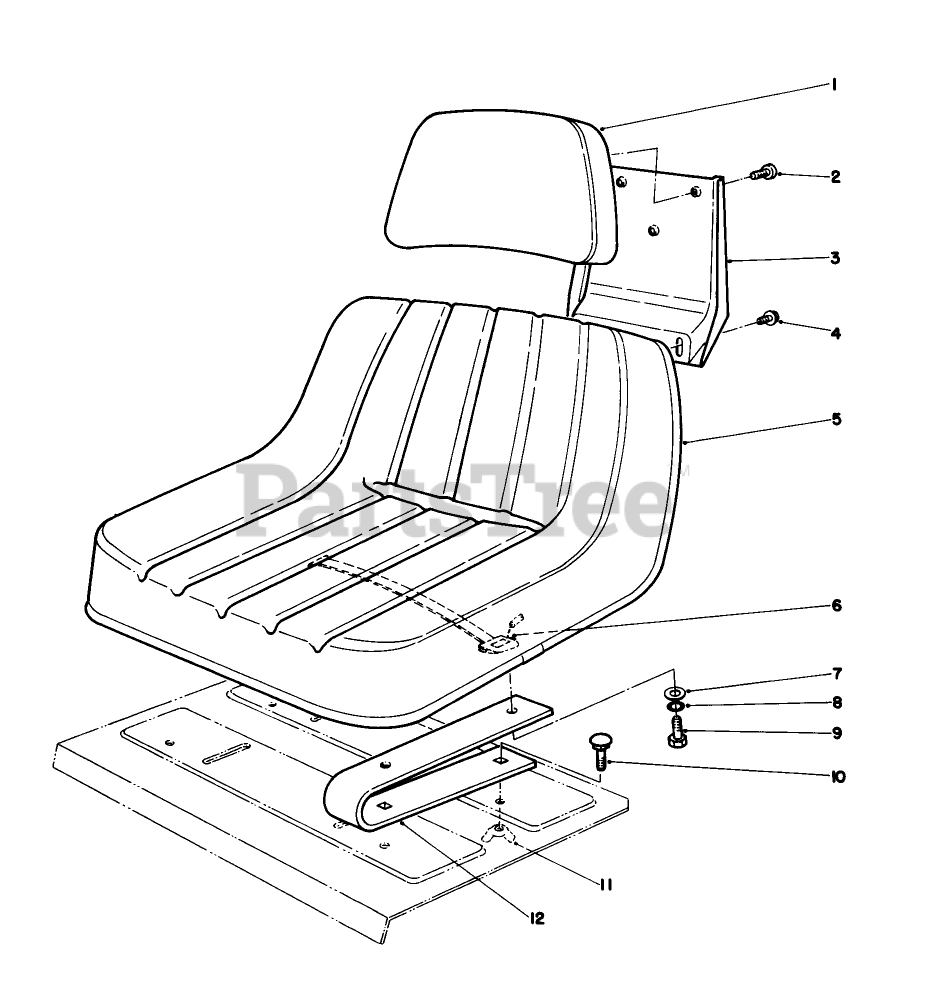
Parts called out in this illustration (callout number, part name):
2	SCREW-HEAD, PAN
4	SCREW-HHF
6	SWITCH-SEAT
7	WASHER-PLAIN
8	WASHER-LOCK
9	SCREW-HH
10	SCREW-CARR
